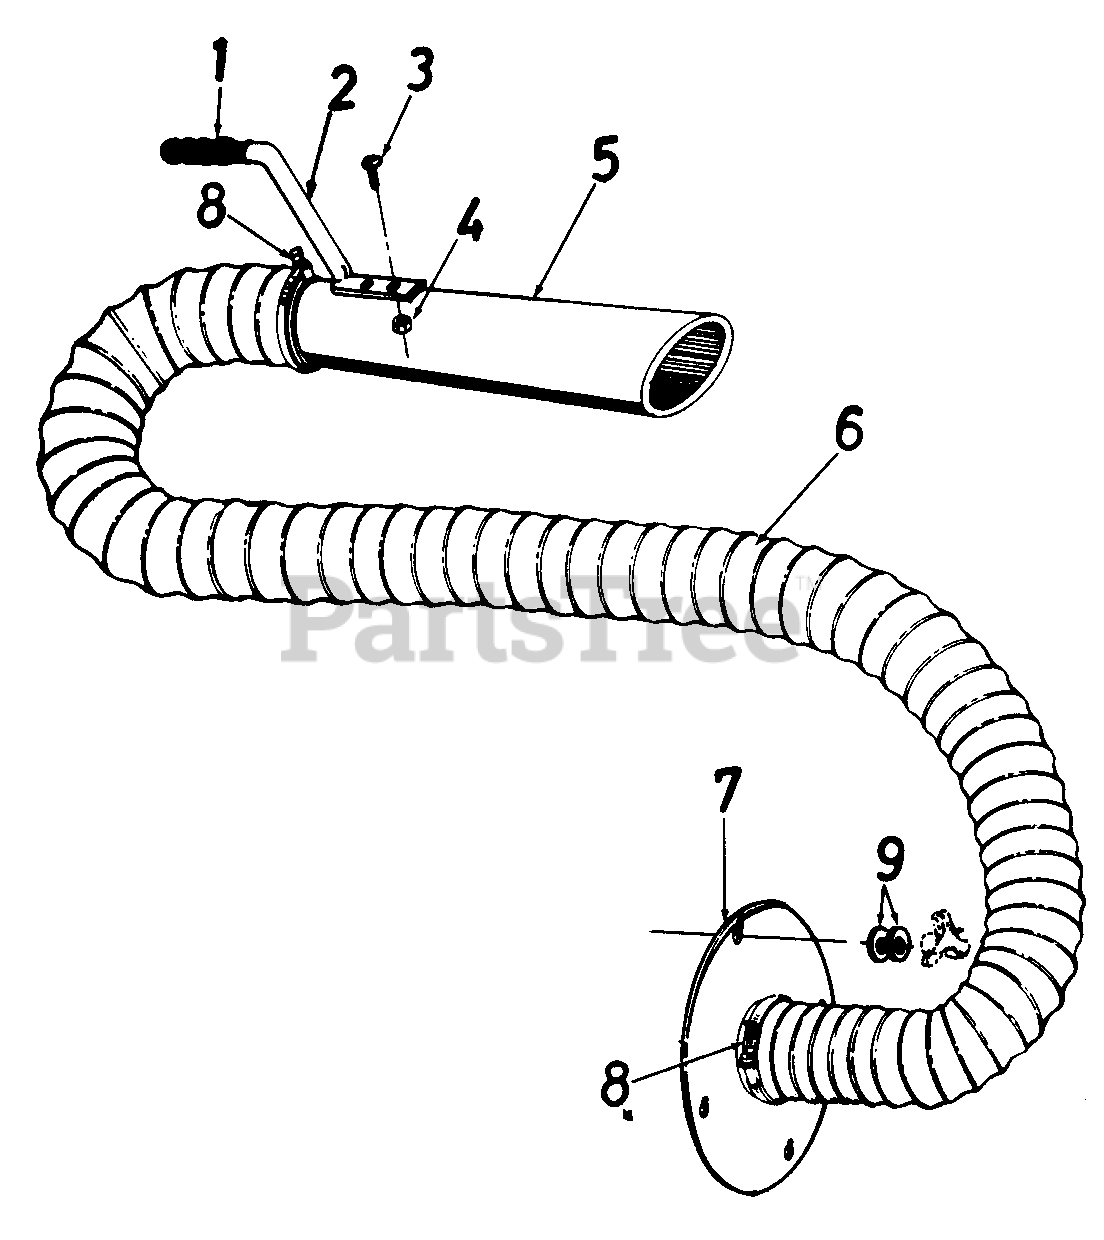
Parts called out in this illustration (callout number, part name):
1	Handle Grip
2	Handle
3	Truss Sems Scr. 10-24 x 1/2" Lg.4
4	Hex Nut 10-24 Thd.*
5	Hose Nozzle
6	Flexible Hose 4" Dia. x 10' Lg.
9	Flat Washer .34 I.D. x 1.12 O.D.
